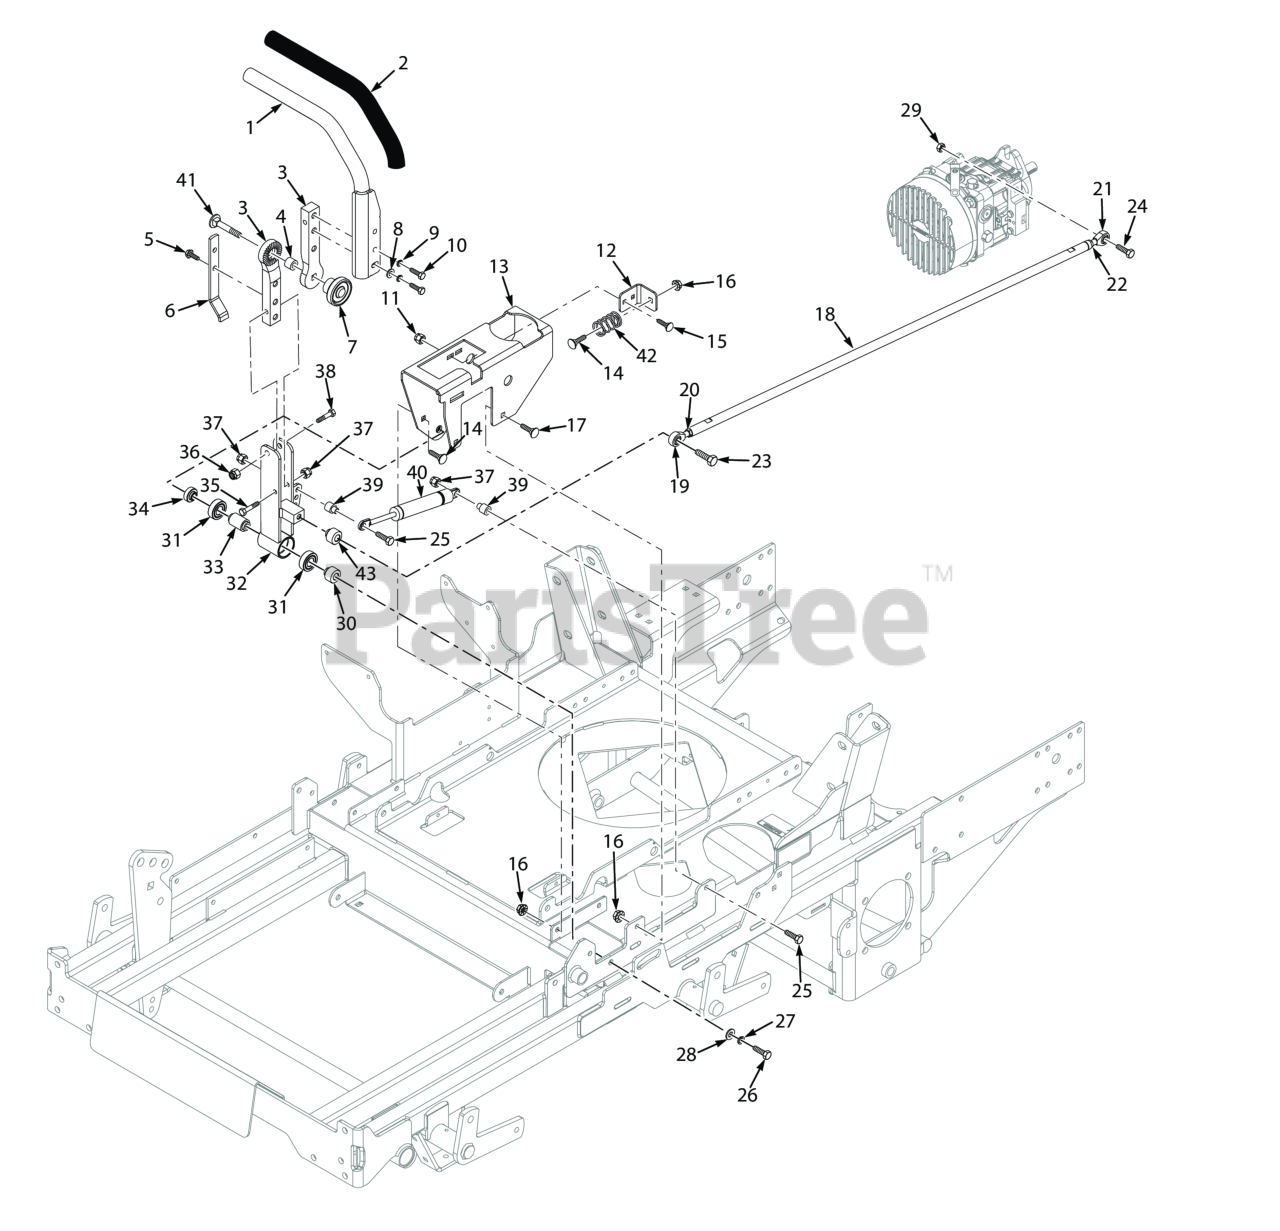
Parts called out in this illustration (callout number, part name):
1	Handle Bar w/Grip - LH
2	Grip, Control Handle
3	ADJUSTMENT ASSY, CNTL HANDLE
4	Spacer, Rubber
5	Capscrew, 5/16-18 x .75 Serrated Flange Hex Head
6	Actuator, Switch
7	Knob, Control Handle
8	Flatwasher, 5/16-.375 x .875 x .083 (35BV & 37BV-EFI)
9	Lockwasher, 5/16 (.317 x .586 x .078) Helical Spring
10	Bolt, Heax Head 5/16-18 x 1" (48V / 52V)
11	Nut, Flanged Elastic Stop 1/4-20
12	Mounting Bracket, Spring Return
13	Control Plate w/Decals LH
14	Bolt, 5/16-18 x .75 RHSN Carriage
15	Serr. Fl. Hex Head CPSCR, 1/4-20 x 3/4"
16	Nut, Serrated Flange 5/16-18 (Right Front Engine Mounting, Briggs and Kohler Only)
17	HHCS, 5/16-18 X .75 FLG
18	Linkage Assy., Pump Control (incl. #19 - #22)
19	Rod End, Male 3/8"-24 LH Thread
20	Nut, 3/8-24 UNF LH Jam
21	Rod End, Male - RH, 3/8-24 Thread
22	Nut, 3/8-24 UNF R.H. Thread
23	Bolt, Hex Head 3/8-16 x 1-3/4" (Kohler EFI)
24	Bolt, Hex Head 3/8-16 x 1-1/4", Kawasaki FX / FS
25	Bolt, Hex Head 5/16-18 x 1-1/2" (Right Front Engine Mounting, Briggs and Kohler Only)
26	Bolt, Hex Head 3/8-16 x 4-1/4"
27	Lockwasher, 3/8" Spring, Kawasaki FX / FS
28	Flatwasher, 3/8" Special (.391 x .938 x .105)
29	Bolt, Hex Head 3/8-16 x 1" Ser. Flg.
30	Spacer, Controls
31	BEARINGS, BALL, NEUTRAL RETURN
32	Control Lever Weldment, RH
33	Spacer, Bearing
34	Spacer, Controls
35	Bolt, Hex Head 5/16-18 x 2-1/2" (x3) (35BV & 37BV-EFI)
36	HEX NUT, ELASTIC STOP LOCK, 3/8-16
37	HEX NUT, ELASTIC STOP LOCK, 5/16-18
38	Capscrew, Hex Head 3/8-16 x 2.0"
39	Spacer, Pump Dampener
40	Gas Damper
41	Bolt, RDHD Carr. 3/8-16 x 1-1/2 (52" & 61")
42	Return Spring, Control Arm
43	SPACER
